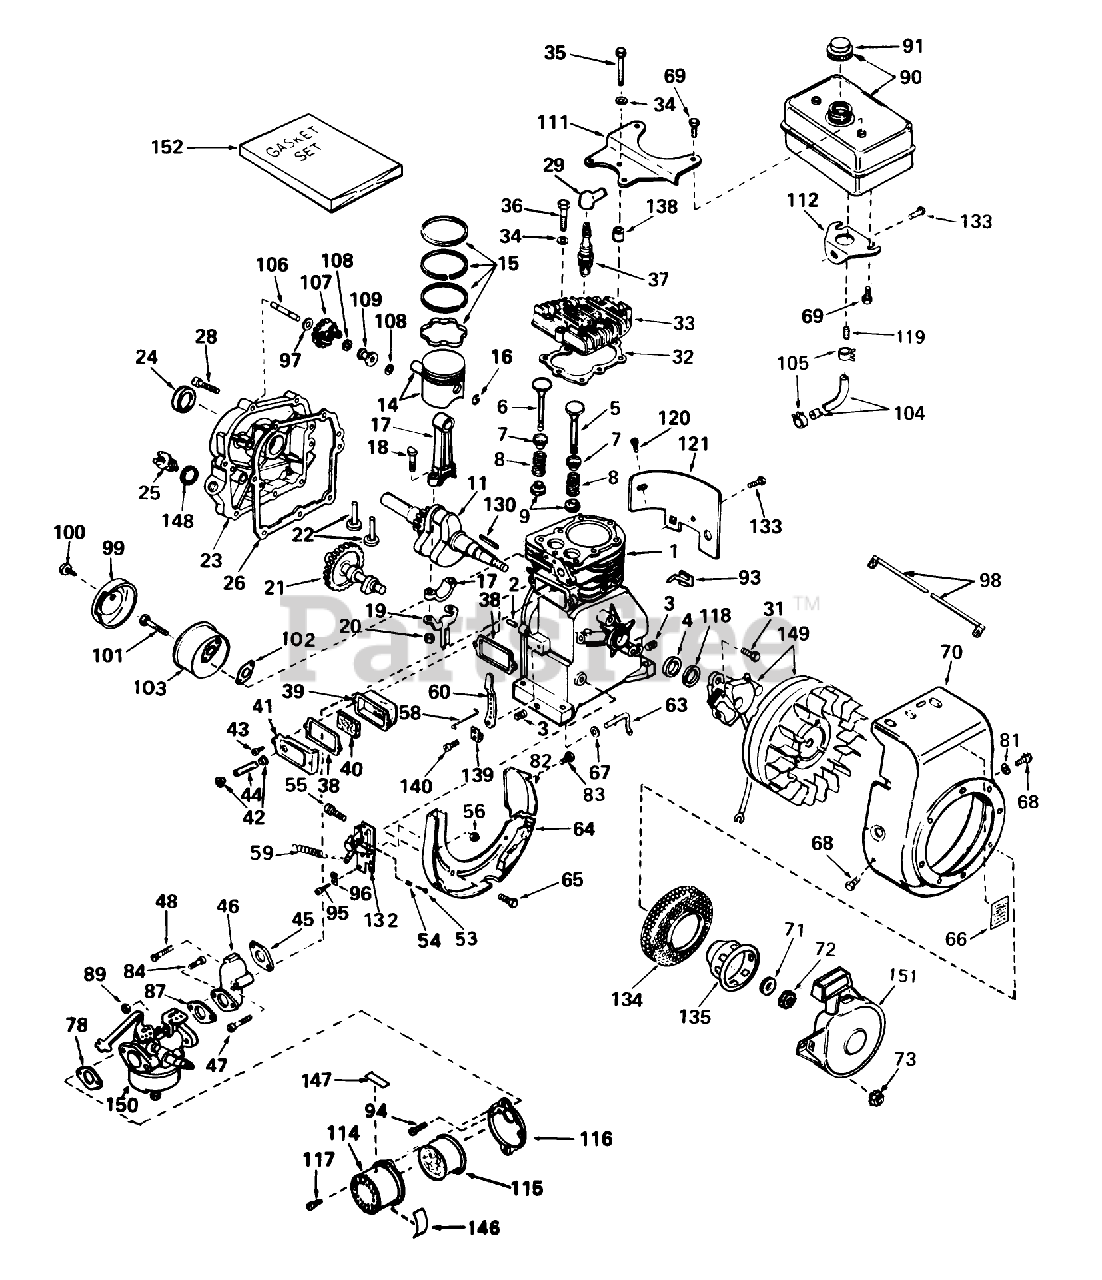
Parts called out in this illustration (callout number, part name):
1	Cylinder Assy. (Incl. Nos. 2,3 4)
2	Pin-Dowel
3	Plug-Drain, Oil (SQH 1/4-18)
4	OIL SEAL
5	Valve, Intake (Incl. Ref. #38, 39 40) (Std.)
5	Valve, Exhaust (1/32" Oversize) (Incl. Nos. 8, 9 10)
6	Valve, Exhaust (Standard) (Incl. Nos. 8, 9 10)
6	Valve, Exhaust (1/32" Oversize) (Incl. Nos. 8, 9 10)
7	Cap-Upper Valve Spring
8	Spring-Valve
9	Cap-Valve, Spring
11	Crankshaft Assy.
14	Piston Pin Assembly (Incl. 2 of No. 16) (Std.)
14	Piston Pin Assembly (Incl. 2 of No. 16) (.010 Oversize)
14	Piston Pin Assembly (Incl. 2 of No. 16) (.020 Oversize)
15	Piston Ring Set Std.
15	Piston Ring Set .010 O.S.
15	Piston Ring Set .020 O.S.
16	Ring-Retaining, Piston Pin
17	Rod Assy., Connecting (Incl. Ref. #17)
18	Bolt, Connecting
19	53020/22 GIL.HYDRO
20	LOCKNUT
21	Camshaft (Compression Release
22	Lifter-Valve
23	Cover, Cylinder (Incl. Nos. 24, 25, 106 148)
24	Seal, Oil
25	Plug-Fill, Oil
26	Gasket-Cylinder Cover
28	Screw
29	Cover-Spark Plug
31	Screw
32	Gasket-Cylinder Head
33	CYLINDER HEAD
34	Washer
35	Screw Hex Hd. Cap
36	Screw
37	Plug, Spark (J17LM or equiv.)
38	Gasket-Breather
39	Body-Breather
40	Element, Breather
41	Gasket-Gear Case
42	GROMMET
43	Screw
44	Breather Tube
45	Gasket-Intake
46	Pipe, Intake
47	Screw (1/4-20 x 1-19/32)
48	Screw
53	Screw
54	Spring-Compression
55	Screw
56	Nut-Lock
58	Jet-Main
59	Spring-Extension
60	Lever-Governor
63	Rod-Governor
64	Baffle-Blower Housing
65	Screw (1/4-20x19/32)
66	INSTRUCTION DECAL
67	Washer-Flat
68	Screw
69	Screw (1/4-15x7/8)
70	Housing, Blower
71	Washer-Spring
72	Hex Nut
73	Nut and Lock Washer (1/4-28)
78	Gasket
81	Washer, Flat
82	Baffle-Extension
83	Screw-Hex Washer Hd.
87	Gasket
89	Nut and Lock Washer (1/4-28)
90	53023/VAR.10/16HP O
91	Cap, Fuel
93	Clip-Wire
94	Screw (10-32 x 1/2)
95	Screw (10-32 x 3/8)
96	Conduit
97	Washer-Flat
98	Wire, Ground
99	Cover-Muffler
100	Screw (1/4-15x7/8)
101	Screw
102	Gasket Exhaust
103	Muffler
104	Line-Fuel
105	Clamp-Line, Fuel
106	Shaft-Governor
107	Governor Gear ASM
108	Ring-Retaining
109	Spool-Governor
111	Plate-Fuel Tank
112	Bracket, Fuel Tank Lower
114	Body
115	AIRCLEANER
116	BRACKET, AIRCLEANER
117	Screw
118	Gasket Stator
119	Spring, Coil
120	Key, Flywheel
121	Extension-Blower
130	Key, Flywheel
132	Bracket Assy., Control (Incl. Nos. 149, 150, 151 152)
133	Screw (1/4-20x19/32)
134	Screen, Starter
135	Cup, Starter
138	pacer
139	Clamp-Lever, Governor
140	Screw
146	Decal, Air Cleaner
147	Decal, "Choke"
148	Gasket, Oil Filler
149	Magneto (The complete magneto is not available as an assembly The magneto number is shown for reference purposes only. Order component parts individually, as shown in parts list.)
150	Carburetor (Incl. Ref. #87)
151	Starter, Rewind
152	Gasket Set (Incl. items marked*
